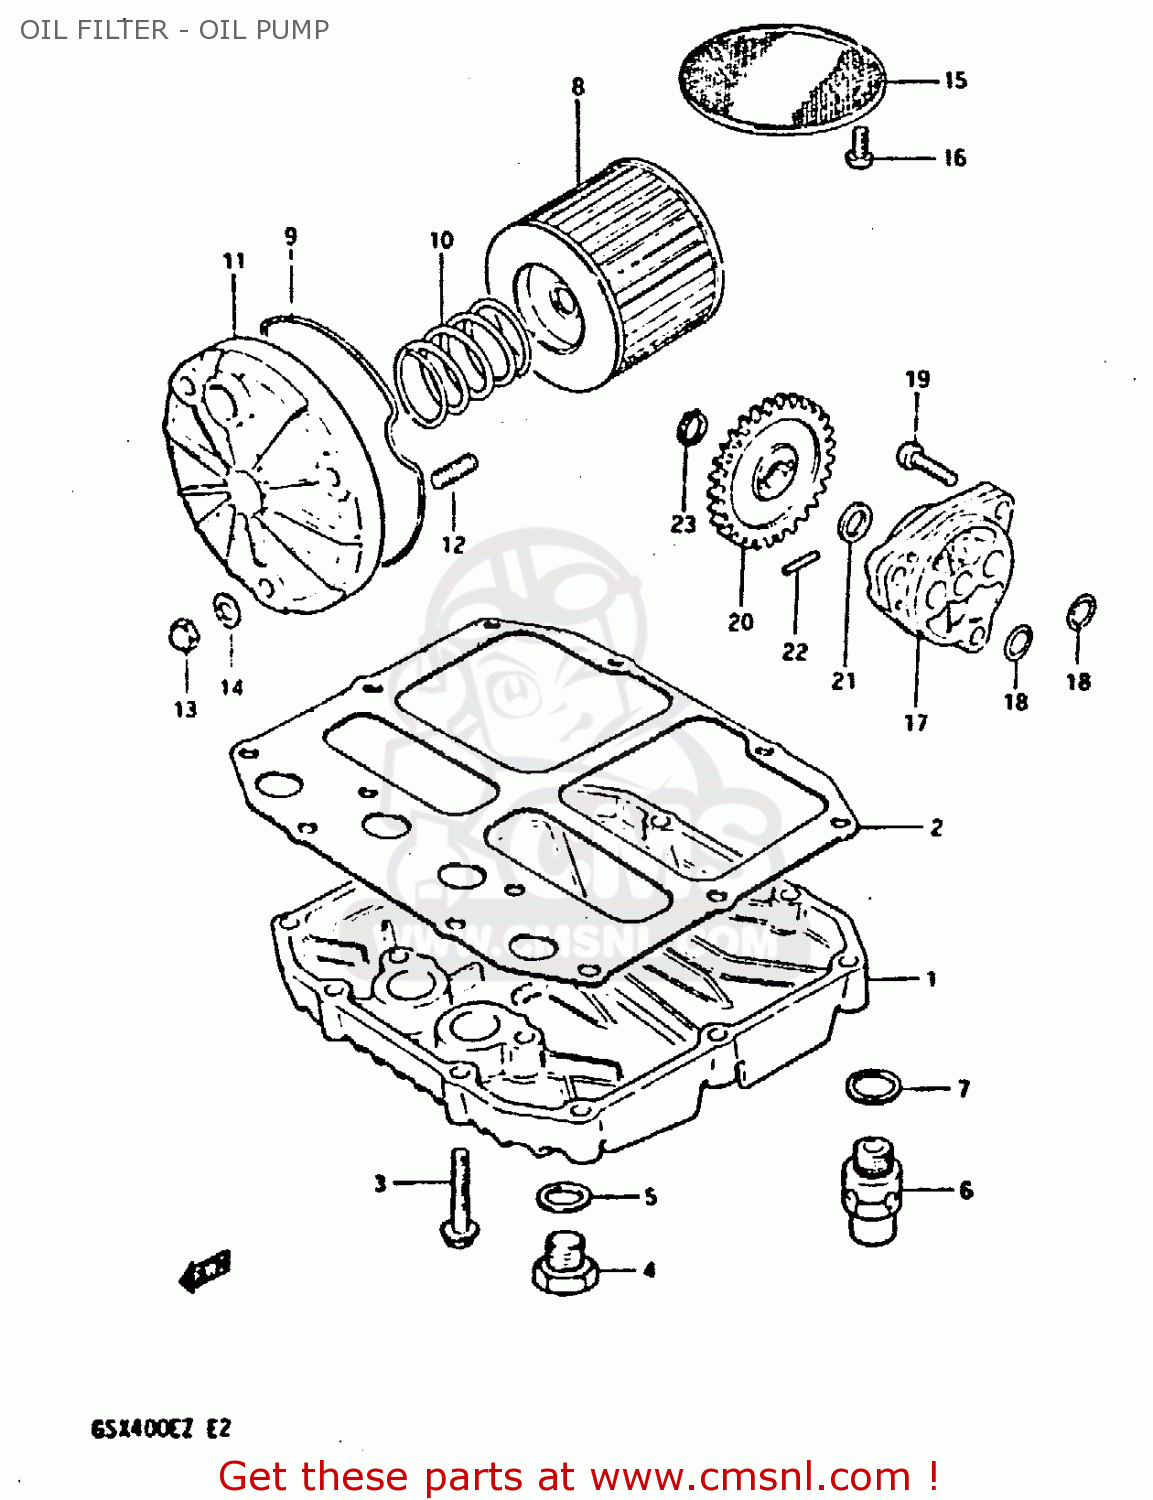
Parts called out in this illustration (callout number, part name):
1	PAN,OIL
2	GASKET,OIL PAN (MCA)
3	BOLT
4	PLUG
5	GASKET(14X19.2X2) (NAS)
6	REGULATOR ASSEMBLY,ENGINE
7	WASHER
8	FILTER ASSY,ENGINE OIL
9	O RING,OIL FILTER CHAMBER CAP
10	SPRING
11	CAP,OIL FILTER
12	STUD 6X20
13	NUT
14	WASHER
15	STRAINER,ENGINE OIL
16	SCREW 6X12
17	PUMP ASSY,ENGINE OIL
18	O RING(D:1.9,ID:13)
19	SCREW
20	GEAR,OIL PUMP DRIVEN
21	SHIM
22	PIN(4X15.8)
23	CIRCLIP
